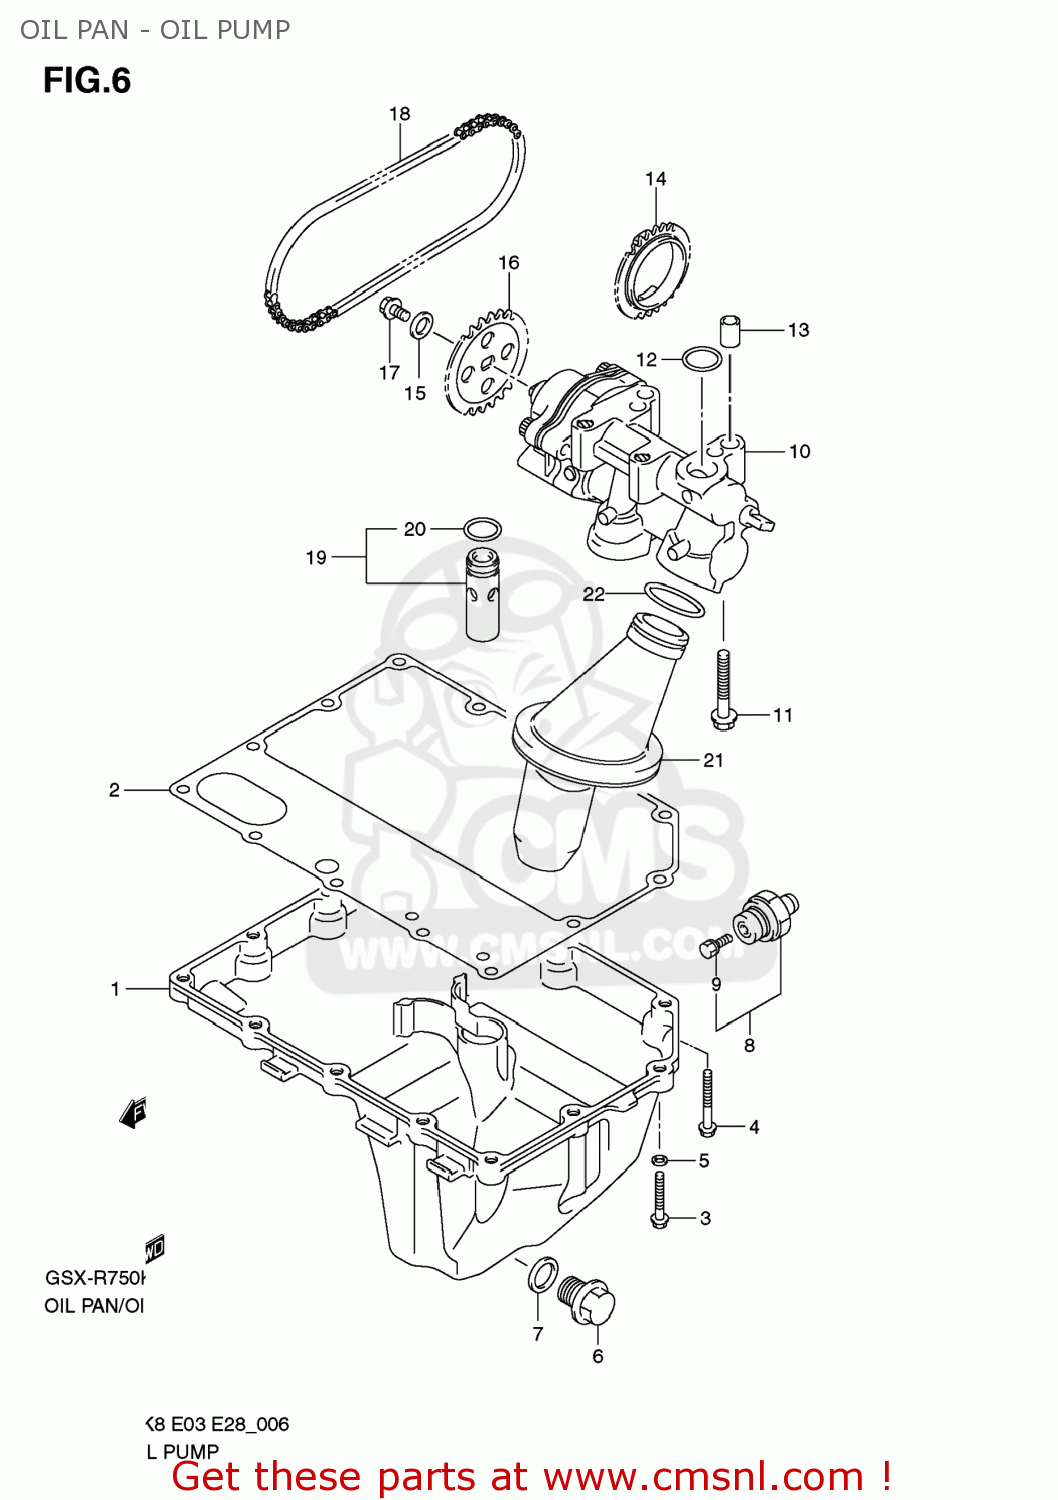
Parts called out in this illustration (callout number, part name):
1	PAN,OIL
2	GASKET,OIL PAN(ASB) (NAS)
3	BOLT
4	BOLT(6X30)
5	GASKET(5.8X13X1.2) (NAS)
6	PLUG(14X20)
7	GASKET(13.8X18.8X4.8) (NAS)
8	SWITCH ASSY,OIL PRESSURE
9	BOLT,OIL PRESSURE SWITCH
10	PUMP ASSY,ENGINE OIL
11	BOLT
12	O RING(D:2.4,ID:15.8)
13	PIN
14	SPROCKET,OIL PUMP DRIVE
15	SHIM(10X18X0.5)
16	SPROCKET,OIL PUMP DRIVEN
17	BOLT(6X12)
18	CHAIN,OIL PUMP DRIVE
19	VALVE ASSY,OIL RELIEF(7K)
20	O RING(D:1.9,ID:13)
21	STRAINER ASSY,ENGINE OIL
22	O RING(D:2.4,ID:24.7)
